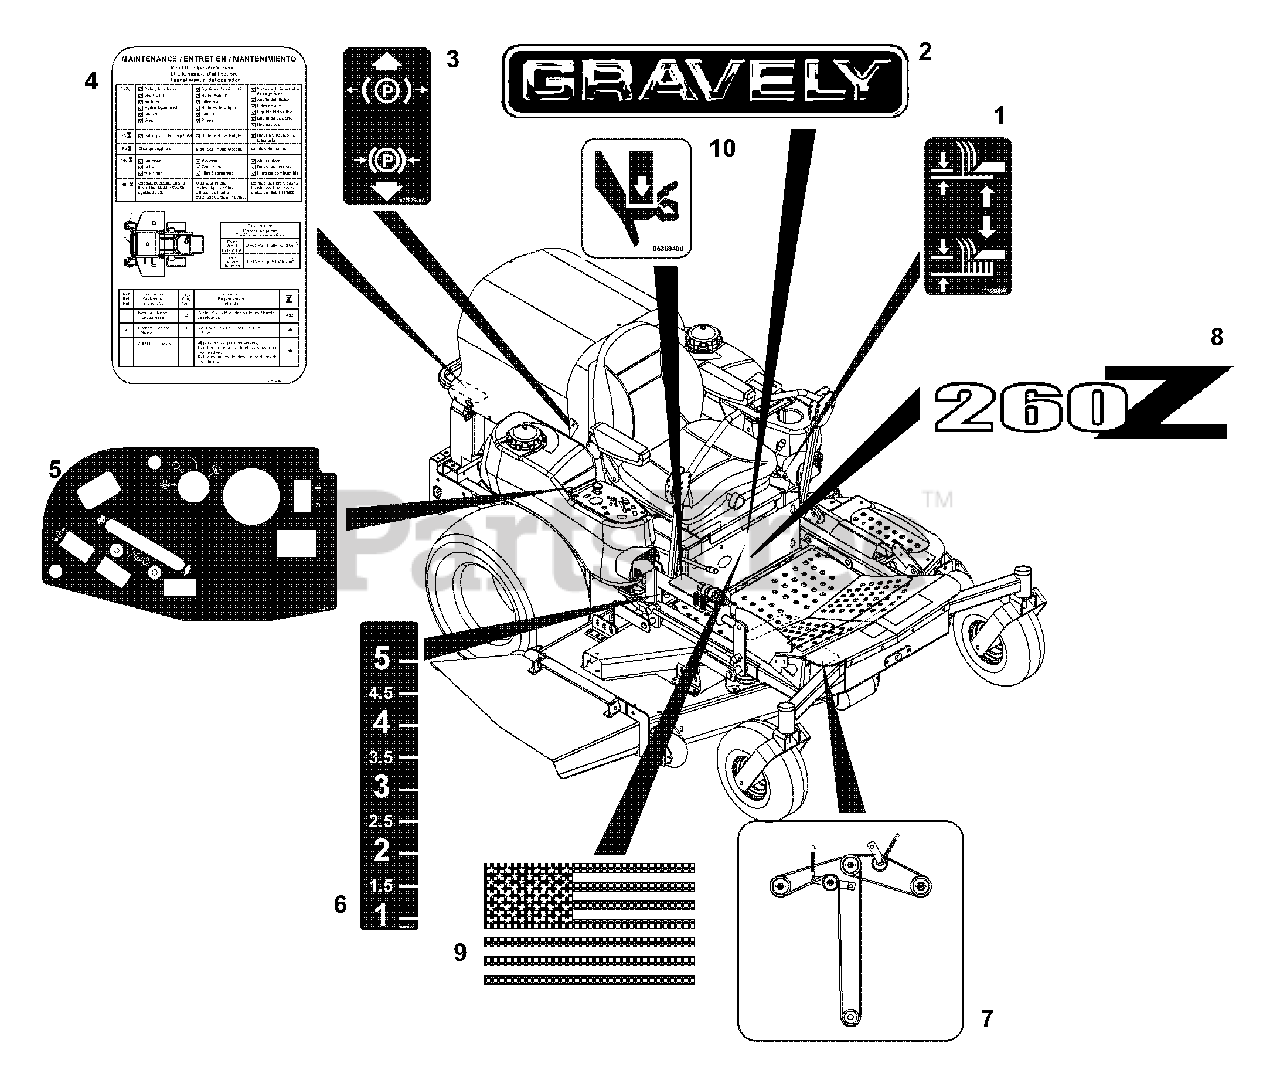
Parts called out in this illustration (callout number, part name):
1	Decal, Lift Lever
2	Decal, 15" Gravely Logo
3	Decal, Parking Brake Lever
4	Decal, Service Instructions
5	Decal, Diesel Control Panel (060, 061,075, 076, 318, 319)
5	Decal, Control Panel (058, 059, 073, 074)
6	Decal, Height of Cut
7	Decal, Belt Diagram (058, 060, 073, 075, 318, 319)
7	Decal, Belt Diagram (059, 061, 074, 076)
8	Decal, PM-260Z (058, 060, 073, 075, 318, 319)
8	Decal, PM-272Z (059, 061, 074, 076)
9	Decal, American Flag
10	Decal, Pinch Point
